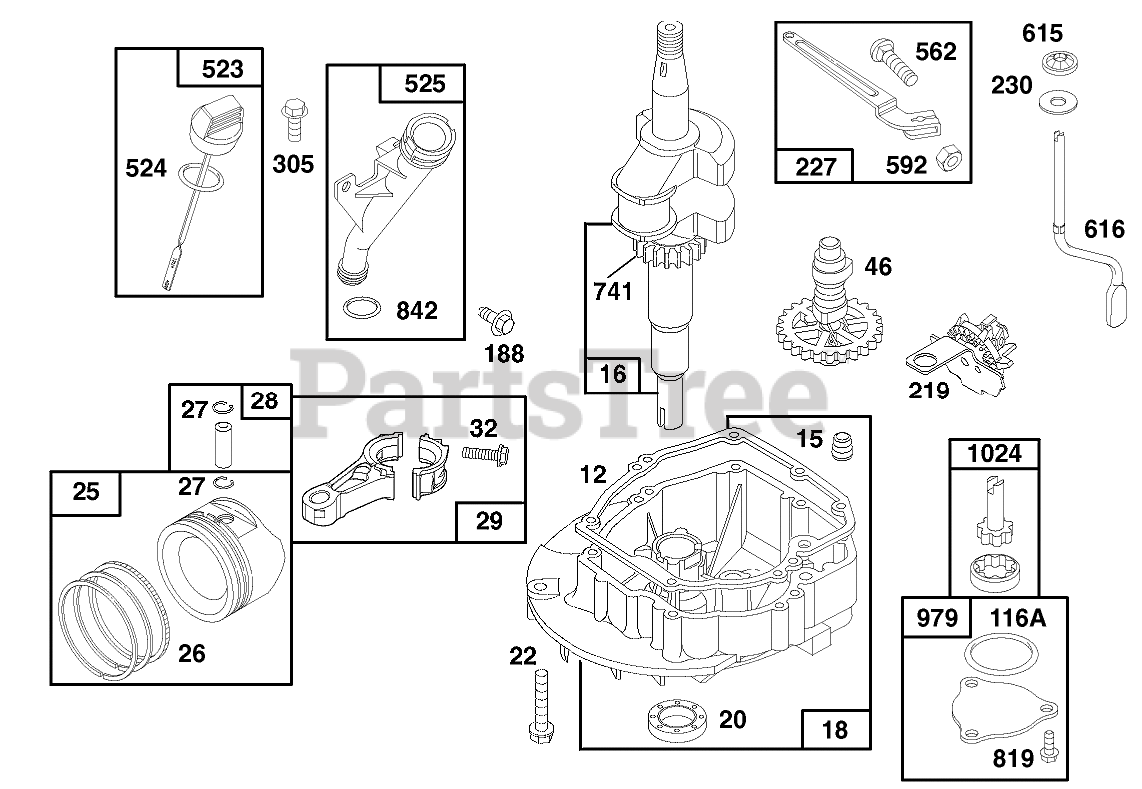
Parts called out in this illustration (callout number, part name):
12	ENGINE BASE GASKET
15	PIPE PLUG
16	CRANKSHAFT
18	ENGINE SUMP
20	SEAL-OIL
22	SCREW - ENGINE BASE
25	STD PISTON ASSEMBLY
26	STD RING SET
27	PISTON PIN LOCK
28	PIN ASM - PISTON
29	CONNECTING ROD
32	Connecting Rod
46	CAM GEAR
116A	O RING SEAL
188	Screw-Cap
219	GOVERNOR/OIL SLINGER
227	GOVERNOR LEVER ASSEMBLY
230	WASHER
305	SCREW - HEX HEAD
523	DIPSTICK-OIL
524	O-RING
525	OIL FILLER TUBE
562	GOVERNOR LEVER BOLT
592	HEX NUT
615	FASTENER
616	GOVERNOR CRANK
741	TIMING GEAR
819	SCREW - SEM
842	O-RING
979	OIL PUMP COVER
1024	OIL PUMP
